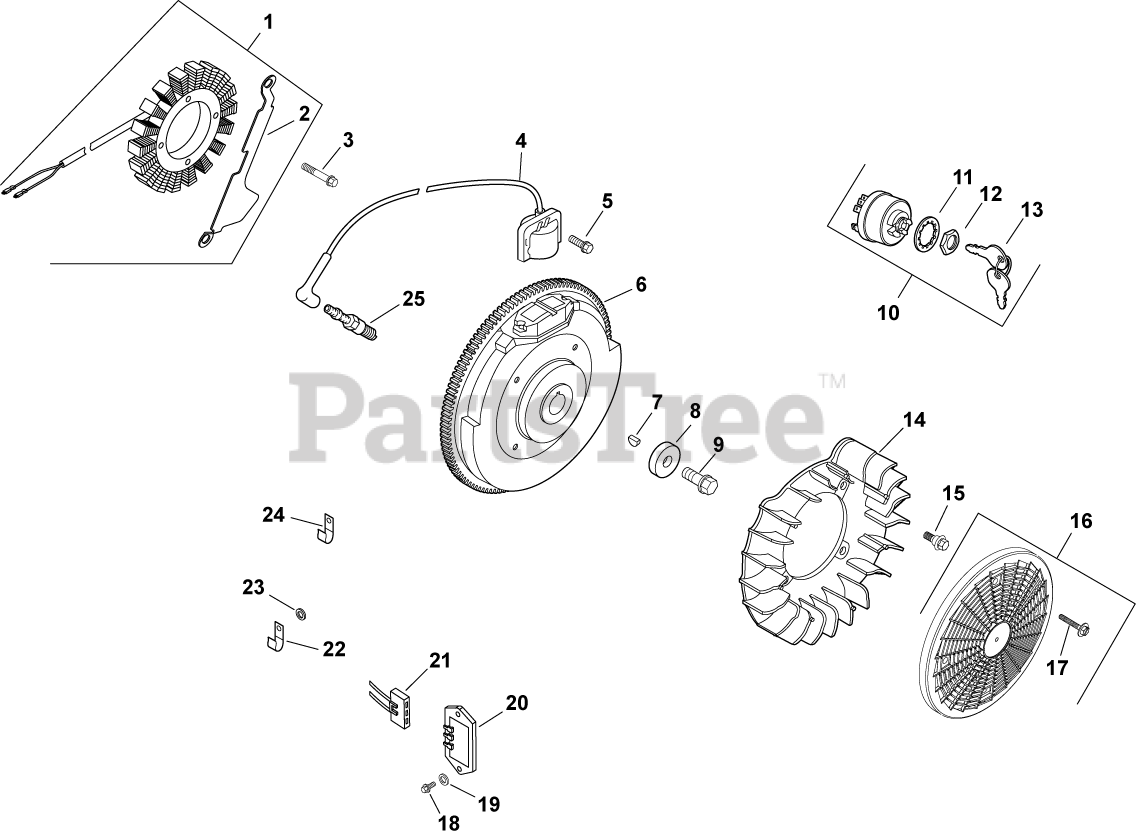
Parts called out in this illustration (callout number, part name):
1	KIT, 15 / 20 AMP STATOR
2	BRACKET, STATOR WIRE
3	SCREW, M5X0.8X25 - (#25086402S)
4	KIT, MODULE IGNTN (CDI FIXED)
5	SCREW, FLG THD FRM M5X.8X20-(#25086399S)
6	FLYWHEEL, PAINTED-USE 24 025 55-S
7	KEY, 3/16" X 5/8"
8	WASHER, FLAT 13/32"
9	SCREW, FLG M10X1.5X45 - (#25086361S)
10	SWITCH ASSY, KEY (KM)-USE 25 099 32-S
11	WASHER, INTERNAL TOOTH
12	NUT, KEY SWITCH
13	KEY, SET -USE 48 340 01-S
14	FAN (WITH HOLE)-USE 24 157 16-S
15	KIT, GRASS SCREEN
16	SCREW, FLG SEMS M4X.7X25
17	BOLT, SHOULDER
18	SCREW, PHL HD #11-16X7/8"
19	WASHER, FLAT 3/16"
20	REG/RECT-15 AMP (KM)-USE 41 403 10-S
21	CONNECTOR, BODY (KM)-USE 25 155 41-S
22	CLIP, CABLE
23	WASHER, FLAT 1/4" (O.D. 1/2")
25	PLUG, SPARK (PRO SERIES)
